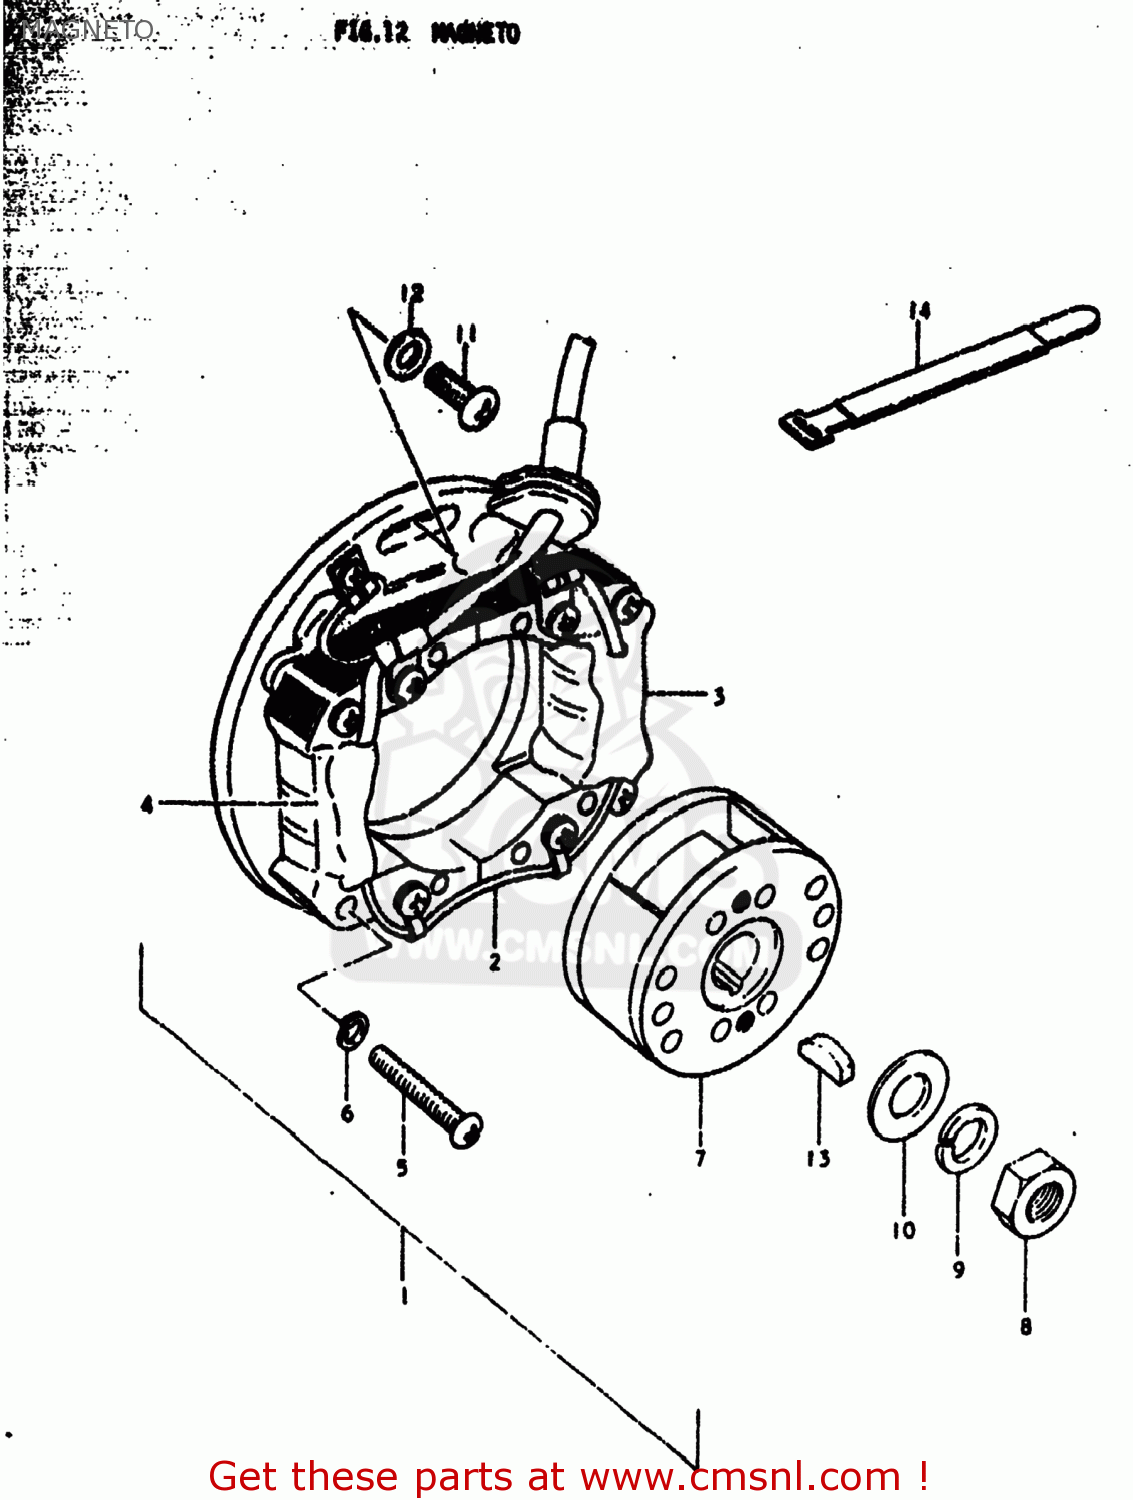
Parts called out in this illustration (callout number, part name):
1	MAGNETO ASSEMBLY
2	STATOR ASSEMBLY
3	COIL,PRIMARY
4	COIL,PULSER
5	SCREW
6	LOCK WASHER
7	ROTOR ASSEMBLY
8	NUT (10MM)
9	LOCK WASHER
10	WASHER
11	SCREW
12	WASHER
13	KEY 4MM
14	CLAMP
